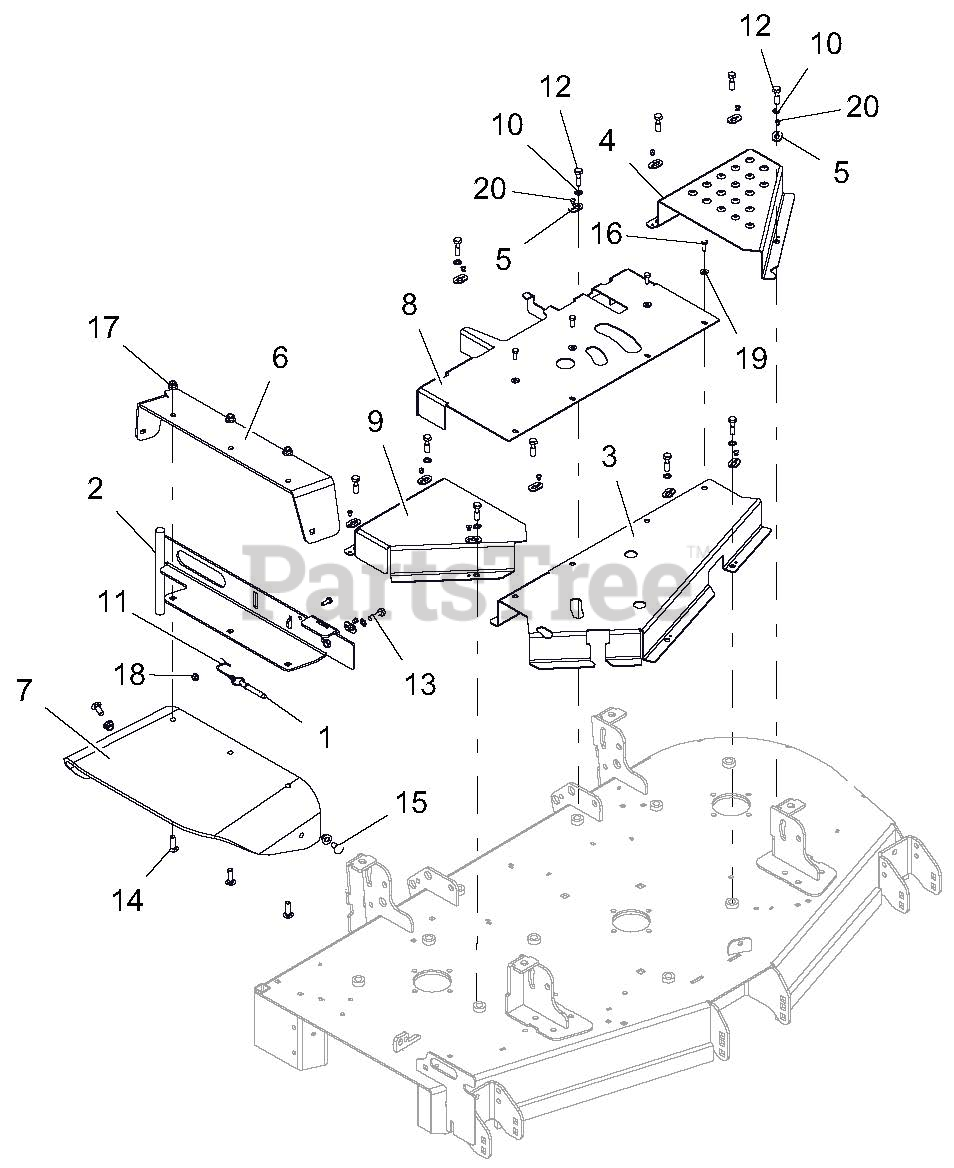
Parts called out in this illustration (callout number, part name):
1	PIN, SPRING BALL .375 OD X 1.50
2	WLDMT, 48" DISCHARGE CHUTE MTG-CE
3	WLDMT, FRONT BELT SHIELD
4	GUARD, LH PT200 CE BELT
5	KEEPER, BOLT
6	SUPPORT, CHUTE MOUNTING BRACKET-RED
7	CHUTE, RUBBER DISCHARGE
8	BRKT, REAR BELT GUARD CE-52
9	BRKT, BELT GUARD RIGHT CE-152
10	LOCK, WSHR-EXT 0.391 X 0.628 X 0.036 YWZC
11	CABLE, 6.0 LANYARD, NYLON
12	BLT, HEX 0.38-16 X 1.25 GR5 CAPTIVE
13	BLT-HEX .38-16X1.25 GR5 CAP .37
14	BLT-RDHDSQNK .38-16X1.25 G5 YWZC
15	BLT-RDHDSQNK .38-16X1.00 G5 YWZC
16	BLT-HEX .25-20X.75 GR5 YWZC
17	NUT-LK-NYL-FLG .38-16 YWZC
18	NUT, LK-TOP-FLG .25-20 YWZC
19	WSHR-FL-STL.281X.62X.065 YWZC
20	RVT-POP .187x.250 (#64) YWZC
